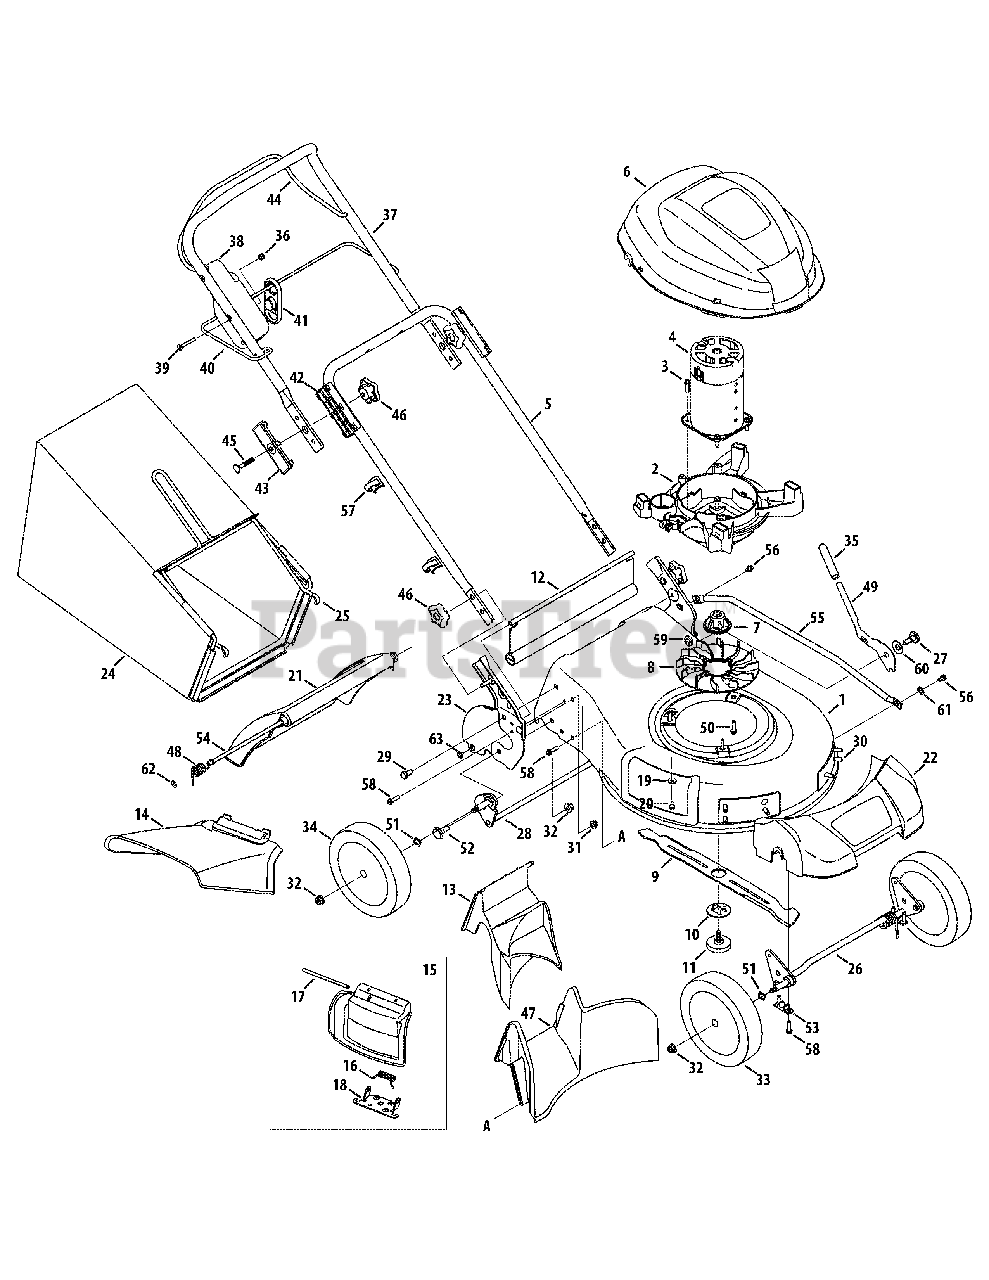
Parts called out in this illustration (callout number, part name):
3	Screw, 1/4-15 x .750
4	Electric Motor, 120V
6	Motor Shroud
7	Blade Hub
8	Electric Fan
9	Mulching Blade
10	Blade Locking Plate
11	Blade Bolt Assembly
12	Trail Shield
13	Rear Mulch Plug
14	Side Discharge Chute
15	Mulch Plug Assembly
16	Torsion Spring
17	Hinge Pin
18	Chute Deflector Adapter
19	Bellville Washer
20	Screw, 1/4-15 x .750
21	Rear Door
22	Front Cover
24	Grass Bag
27	Screw, Shoulder, .50 x .66
29	Screw, 5/16-18 x .625
30	Screw, 5/16-14 x .750
31	Nut, Flange Lock, 5/16-18
32	Nut, Flange Lock 3/8-16
33	Front Wheel
34	Rear Wheel
35	Foam Grip
36	Nut, Hex Lock, 1/4-20
37	Upper Handle
38	Motor/Blade Control
39	Screw, Flat, 1/4-20 x 1.75
42	Lower Handle Insulator
43	Upper Handle Insulator
44	Motor/Blade Control Handle
45	Bolt, Carriage, 5/16-18 x 2.50
46	Star Knob
47	Rear Baffle
48	Door Torsion Spring - RH
48	Door Torsion Spring - LH
49	Spring Lever
50	Screw, 5/16-12 x .750
51	Washer, Wave, .510 x .750 x .017
52	Screw, Shoulder, .500 Dia x .434
53	Bushing, Lock, .505 Dia x .62
54	Rear Door Pivot Rod
57	Cable Guide
58	Screw, 1/4-15 x 1.000
59	Spacer, .515 x 1.00 x .310
60	Washer, Bell .510 x 1.14 x .040
61	Washer Wave, .390 x .825 x .016
62	Nut, Speed
63	Screw, #10-16 x .375
